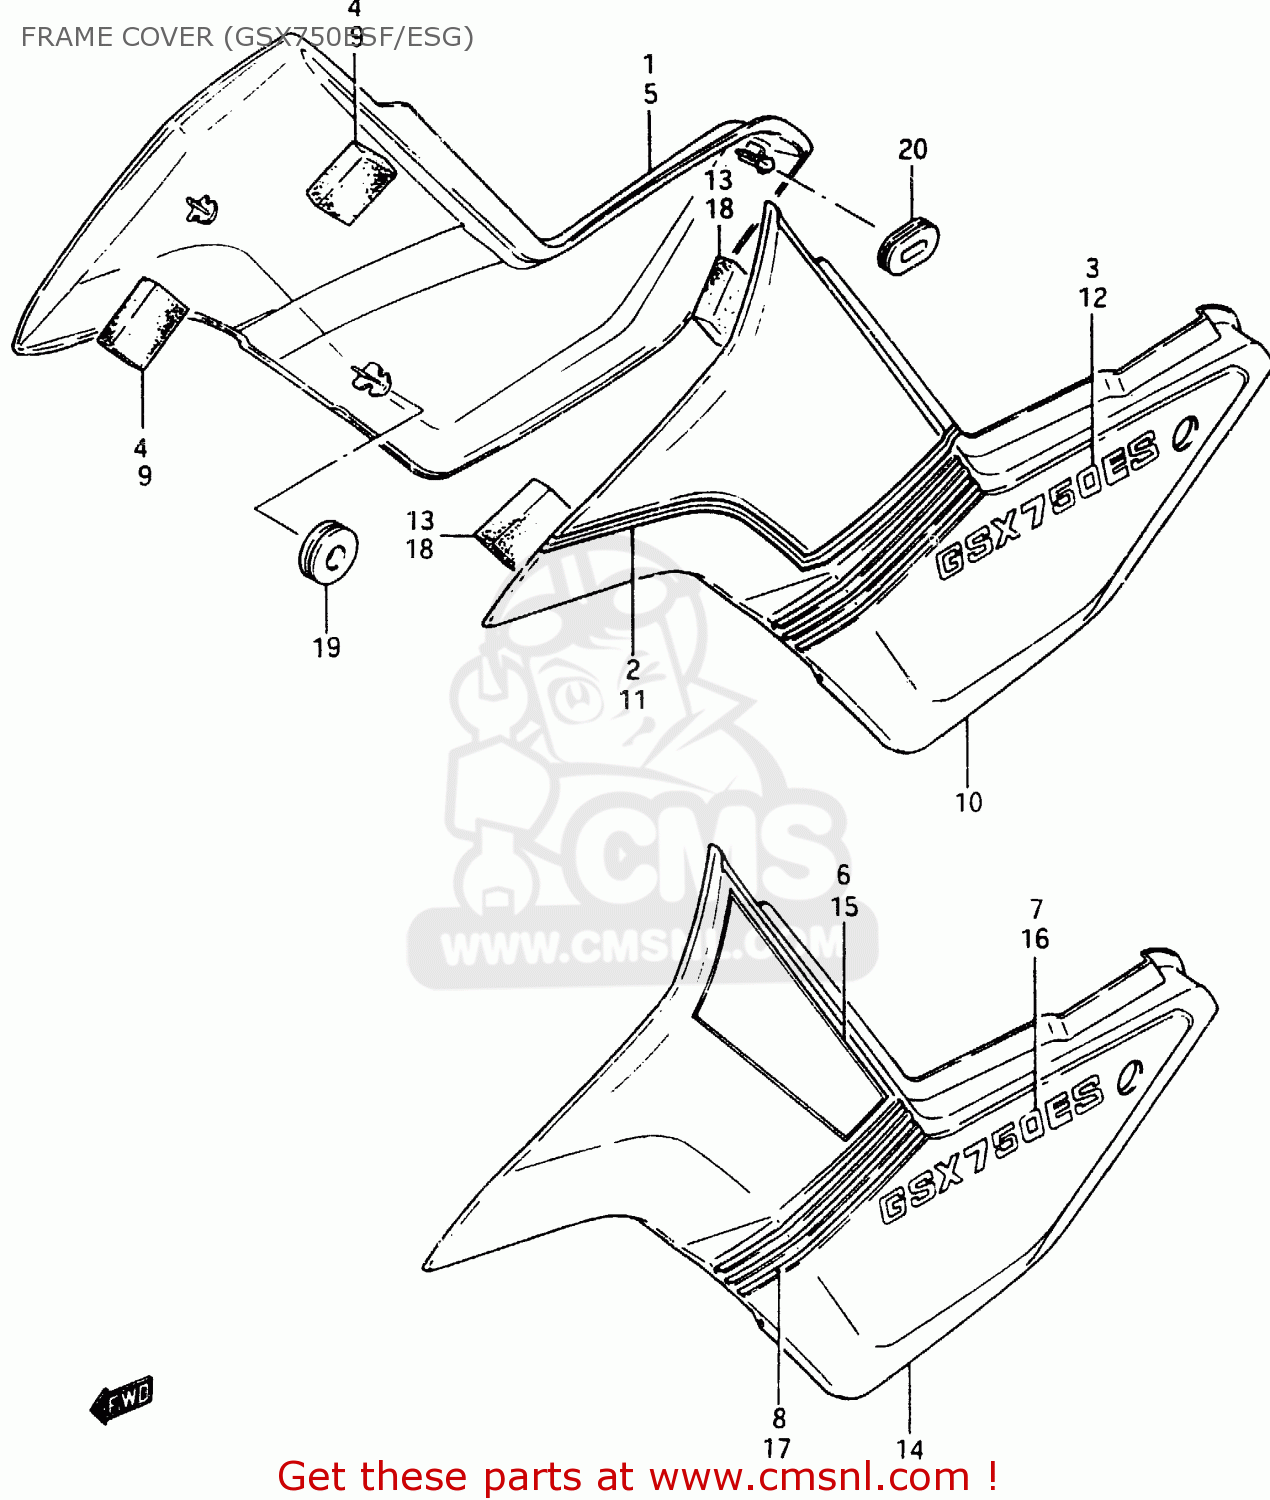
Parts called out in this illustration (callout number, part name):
1	COVER, FRAME RH
2	TAPE SET, FRAME COVER RH
3	EMBLEM
4	CUSHION
5	COVER,FRAME RH
6	TAPE SET, FRAME COVER RH
7	EMBLEM
8	LABEL, DENT RH (SILVER)
9	CUSHION
10	COVER, FRAME LH
11	TAPE SET, FRAME COVER LH
12	EMBLEM
13	CUSHION
14	COVER,FRAME LH
15	TAPE SET, FRAME COVER LH
16	EMBLEM
17	LABEL, DENT LH (SILVER)
18	CUSHION
19	CUSHION
20	CUSHION
